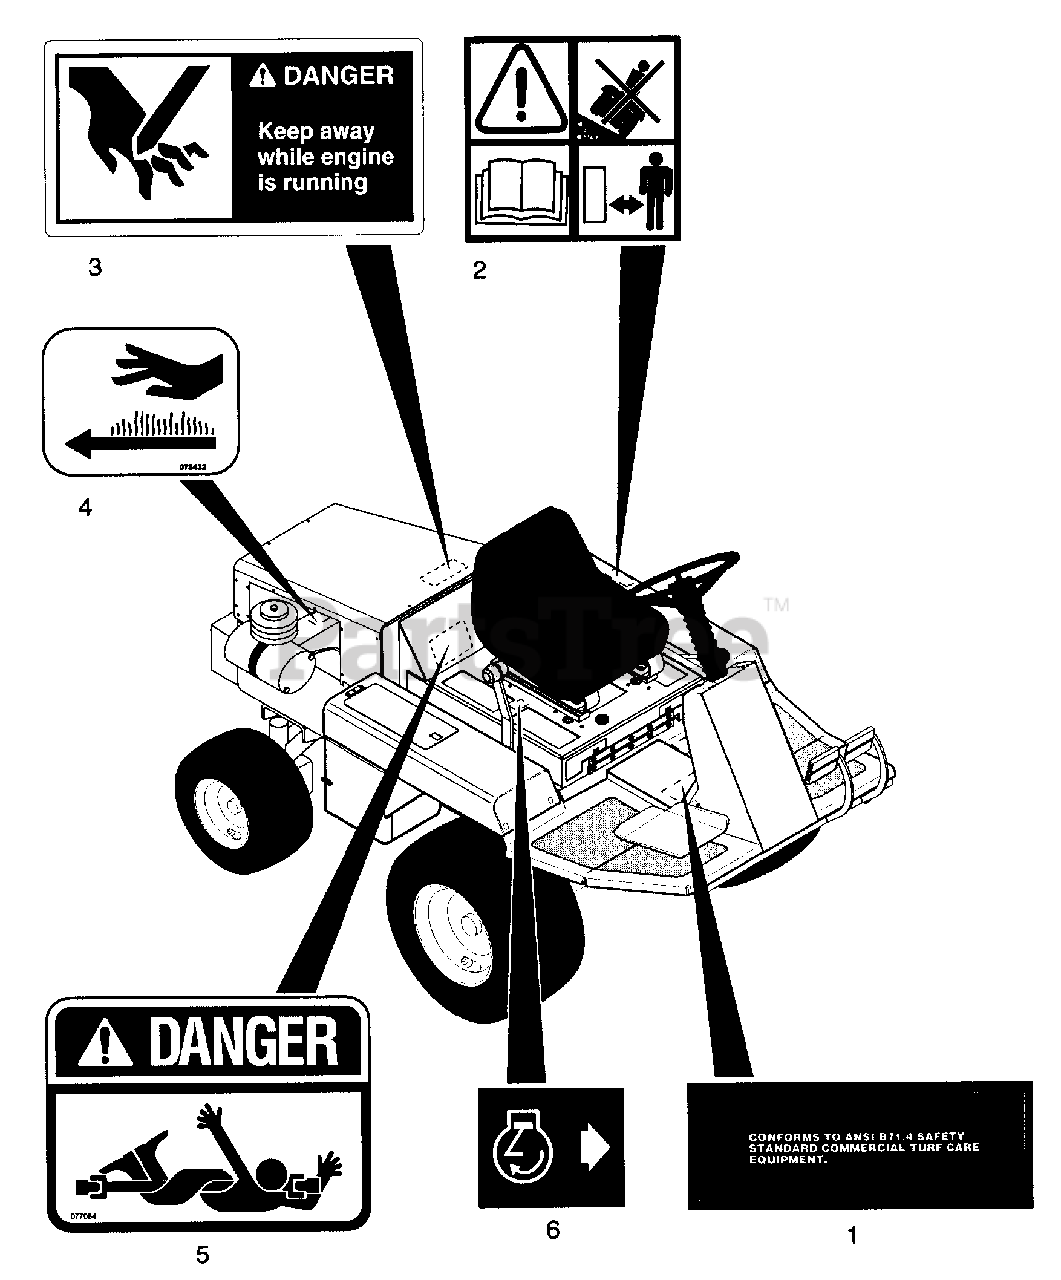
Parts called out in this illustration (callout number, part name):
1	Decal - ANSI
2	Decal -Internation Symbols (990300 only)
3	Decal - Danger Hand
4	Decal - Hot Surface
5	Decal - PTO Danger
6	Decal - Start
